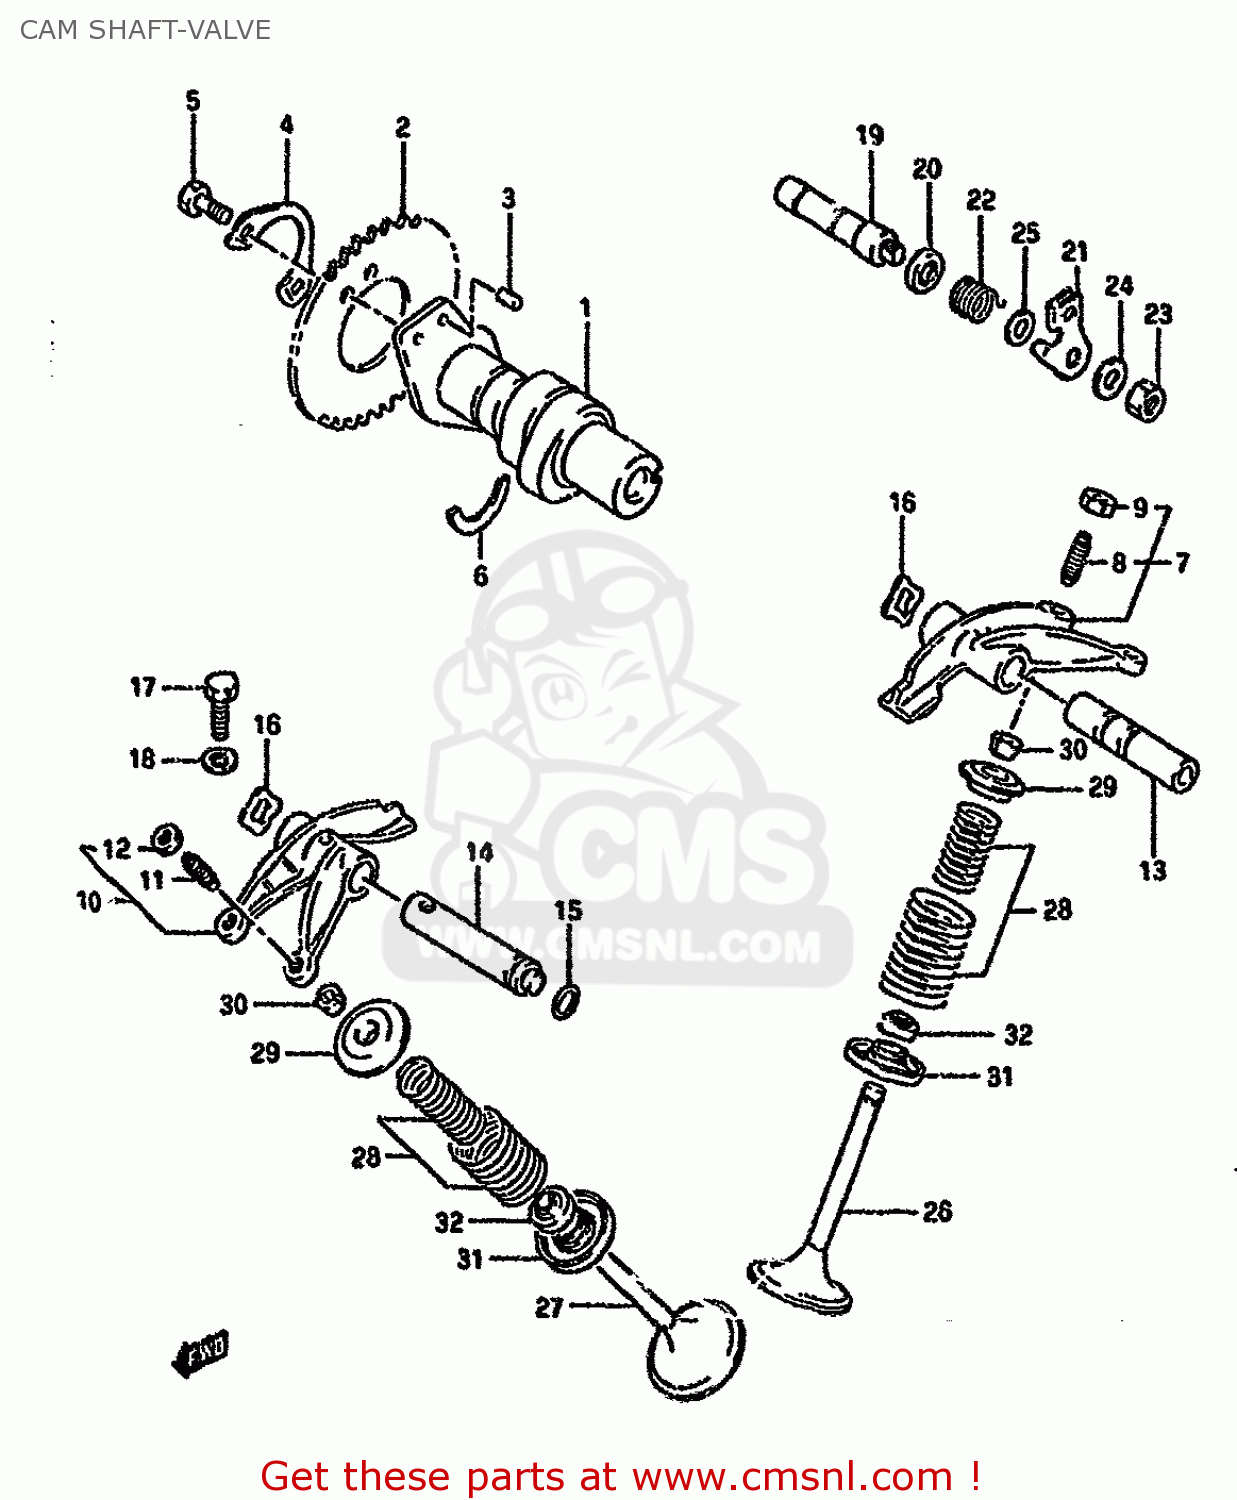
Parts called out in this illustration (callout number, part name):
1	CAMSHAFT
2	SPROCKET,CAMSHAFT(NT:42)
3	PIN
4	WASHER,CAM CHAIN SPROCKET
5	BOLT(6X12.5)
6	C RING
7	ARM,VALVE ROCKER INTAKE
8	SCREW,TAPPET ADJUSTING
9	NUT,ADJUSTING SCREW
10	ARM,VALVE ROCKER EXHAUST
11	SCREW,TAPPET ADJUSTING
12	NUT,ADJUSTING SCREW
13	SHAFT,VALVE ROCKER ARM INTAKE
14	SHAFT,EXHAUST VALVE ROCKER ARM
15	O RING(D:1.9,ID:8.6)
16	WASHER
17	BOLT
18	GASKET(5.8X13X1.2) (NAS)
19	SHAFT,DECOMP
20	SEAL,OIL(10X17X6)
21	LEVER,DECOMPRESSION SHAFT
22	SPRING
23	NUT
24	WASHER
25	WASHER(8.5X13X1.6)
26	VALVE,INTAKE
27	VALVE,EXHAUST
28	SPRING SET,VALVE
29	RETAINER,VALVE SPRING
30	COTTER VALVE
31	SEAT,VALVE SPRING
32	SEAL,OIL(7X14.4X9)
